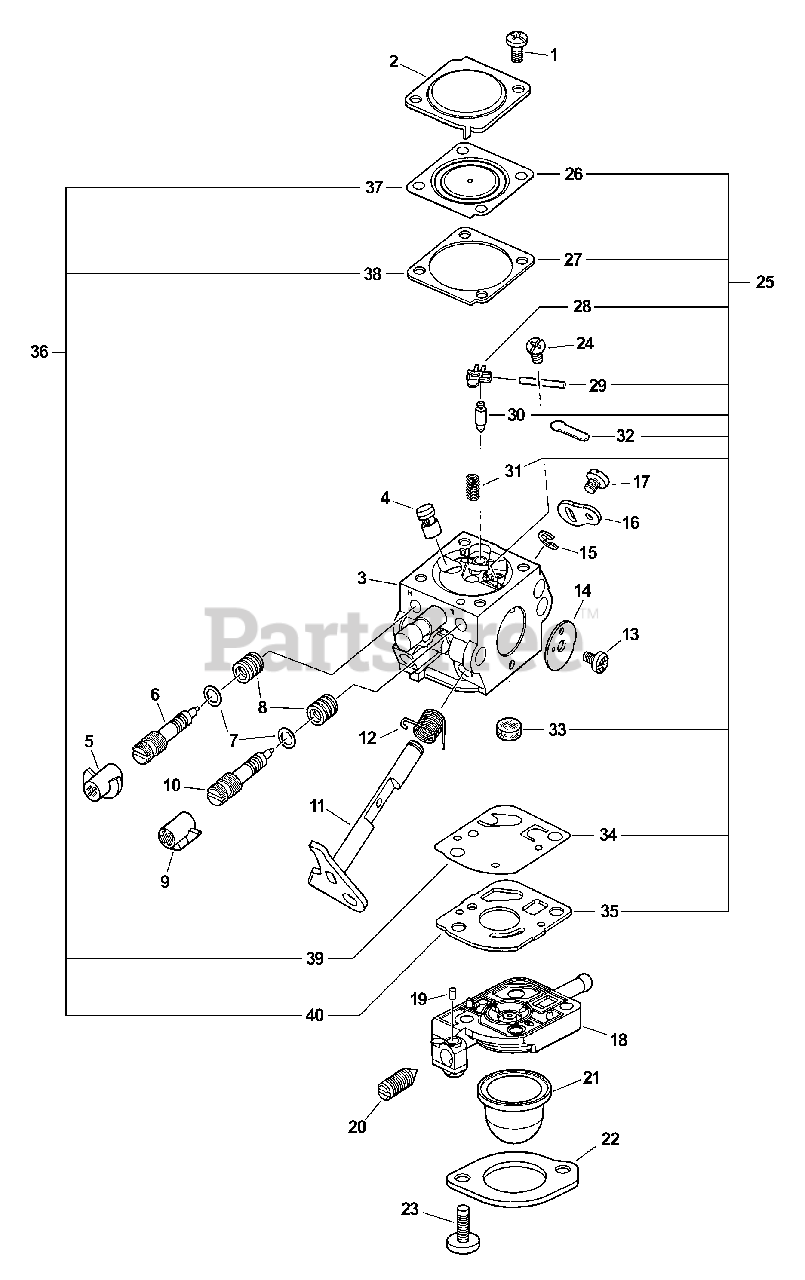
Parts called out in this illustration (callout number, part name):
2	COVER, METERING
3	BODY, CARBURETOR
4	NOZZLE, CHECK VALVE
5	CAP, LIMITER
6	NEEDLE - HIGH SPEED
9	CAP, LIMITER
10	NEEDLE - LOW SPEED
11	SHAFT, THROTTLE
12	SPRING, TRIGGER
14	VALVE, THROTTLE
15	SHAFT, THROTTLE
16	LEVER, THROTTLE
18	BASE, PURGE
19	PIECE, FRICTION
20	SCREW, IDLE ADJUST
21	BULB, PURGE
22	RETAINER, PURGE BULB
23	SCREW, RETAINER
24	SCREW, METERING LEVER PIN
25	REPAIR KIT
26	DIAPHRAGM, METERING
27	GASKET, METERING
28	LEVER, METERING
29	PIN, METERING LEVER
30	VALVE, INLET NEEDLE
31	SPRING, METERING LEVER
32	PLUG, WELCH
33	STRAINER
34	DIAPHRAGM, PUMP
35	GASKET, PUMP
36	DIAPHRAGM/GASKET KIT
37	DIAPHRAGM, METERING
38	GASKET, METERING
39	DIAPHRAGM, PUMP
40	GASKET, PUMP
